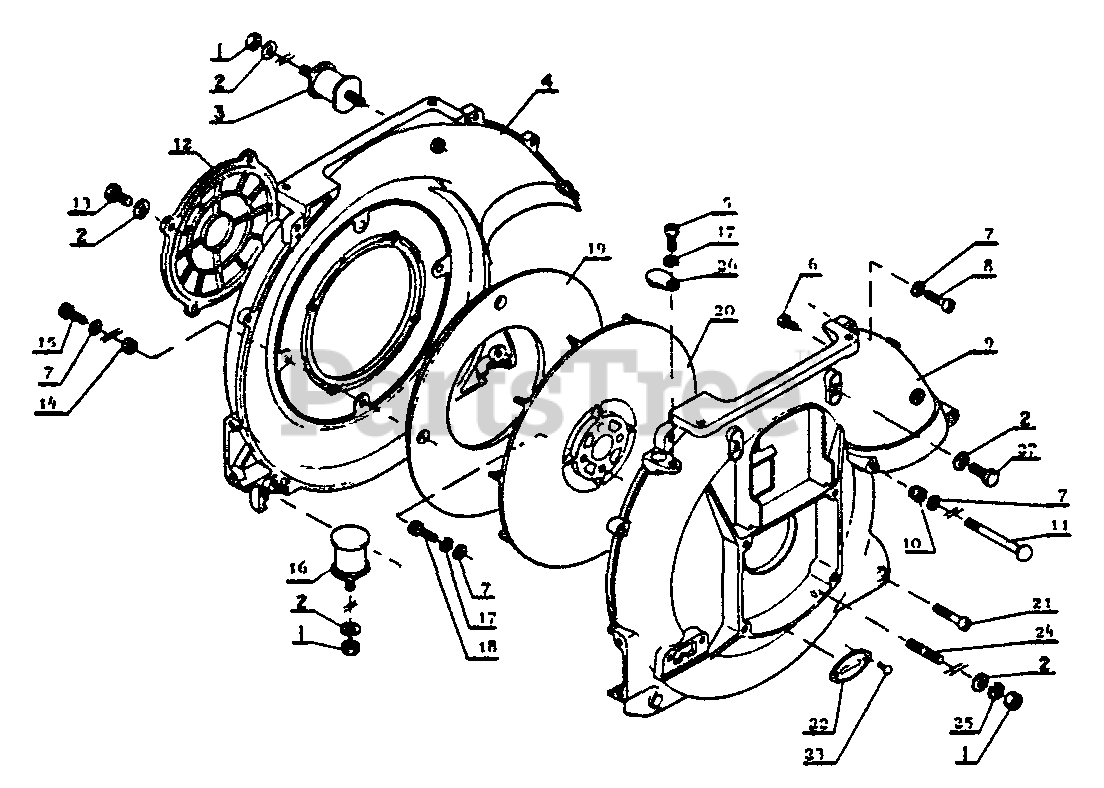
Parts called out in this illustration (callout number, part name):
1	LOCKNUT - 6
2	WASHER - 6
4	COVER, FAN - INNER
5	SCREW - 5X10
6	SCREW - 4X8
7	WASHER - 5
8	SCREW - 5X20
9	COVER, FAN - OUTER
10	NUT - 5
11	BOLT, ELBOW
12	GUARD, DEBRIS
13	BOLT - 6X10
15	BOLT - 5X12
17	LOCKWASHER - 5
18	BOLT - 5X16
19	SEPARATER
21	SCREW - 5X25
22	PLATE, MODEL
23	RIVET
24	STUD
25	LOCKWASHER - 6
26	PLUG
27	BOLT - 6X14
